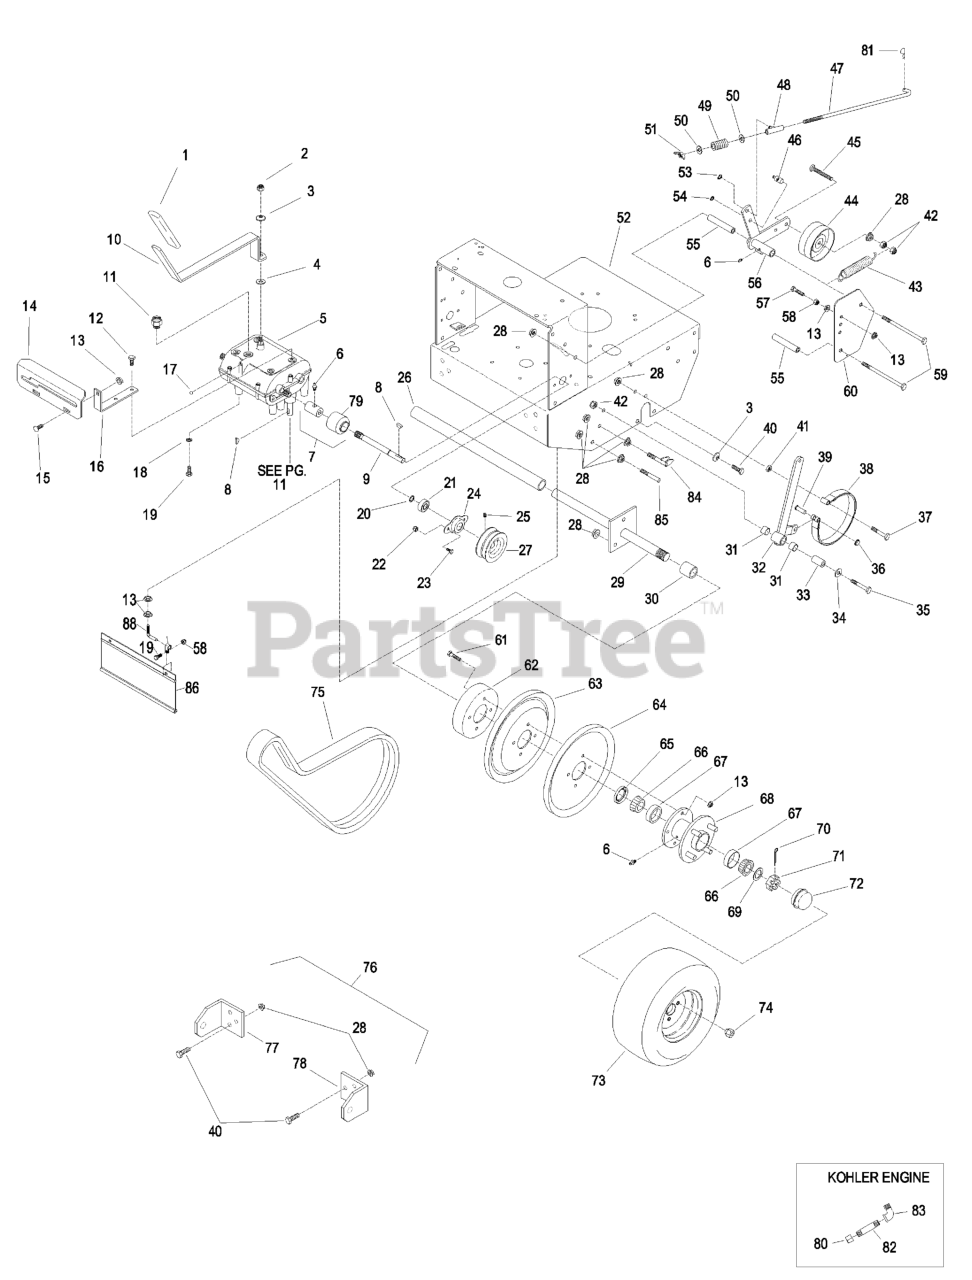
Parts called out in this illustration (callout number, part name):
7	ASM,COUPLER/ZERK
9	SHAFT-TRANSMISSION
11	SWITCH-START, NEUTRAL
16	BRACKET-PLATE, SHIFT
17	BALL,DETENT (SERVICE ONL
18	WASHER-LOCK
21	BEARING-SHAFT
24	FLANGE-OUTPUT
25	SCREW-SET
26	SLEEVE,AXLE
30	SPACER,WHEEL SHORT
31	SLEEVE-BUSHING
33	BUSHING-PIVOT
36	RING-RETAIN,PUSH,EXT,FLAT
38	BAND-BRAKE
39	PIN-CLEVIS
43	SPRING-EXTENSION
44	IDLER-WHEEL, DRIVE
46	SWIVEL-SHORT, ADJUSTABLE
47	LINKAGE-BRAKE
49	SPRING-COMPRESSION
51	WINGNUT-NYLOCK
55	SPACER-SHIELD
56	WLD,ARM RH
60	SHIELD,WHEEL DRIVE
62	DRUM-BRAKE
63	SHEAVE,WHEEL DRIVE
64	SHEAVE,WHEEL DRIVE
65	SEAL-GREASE
66	Cone-Bearing Tapered Roller
67	CUP-BEARING
68	HUB/WHEEL ASM
69	WASHER-SPACER
70	PIN-COTTER
71	NUT-SHH
72	CAP-GREASE
73	WHEEL AND TIRE ASM
75	BELT,WHEEL DRIVE BANDED
76	Kit, Sulky Hitch
78	BRACKET,SULKY RH
80	CAP-HEX
81	PIN-COTTER
82	NIPPLE
83	FITTING-ELBOW-90
84	SCRAPER
87	CLIP-LOOM
88	MOUNT,DRAG SHIELD
